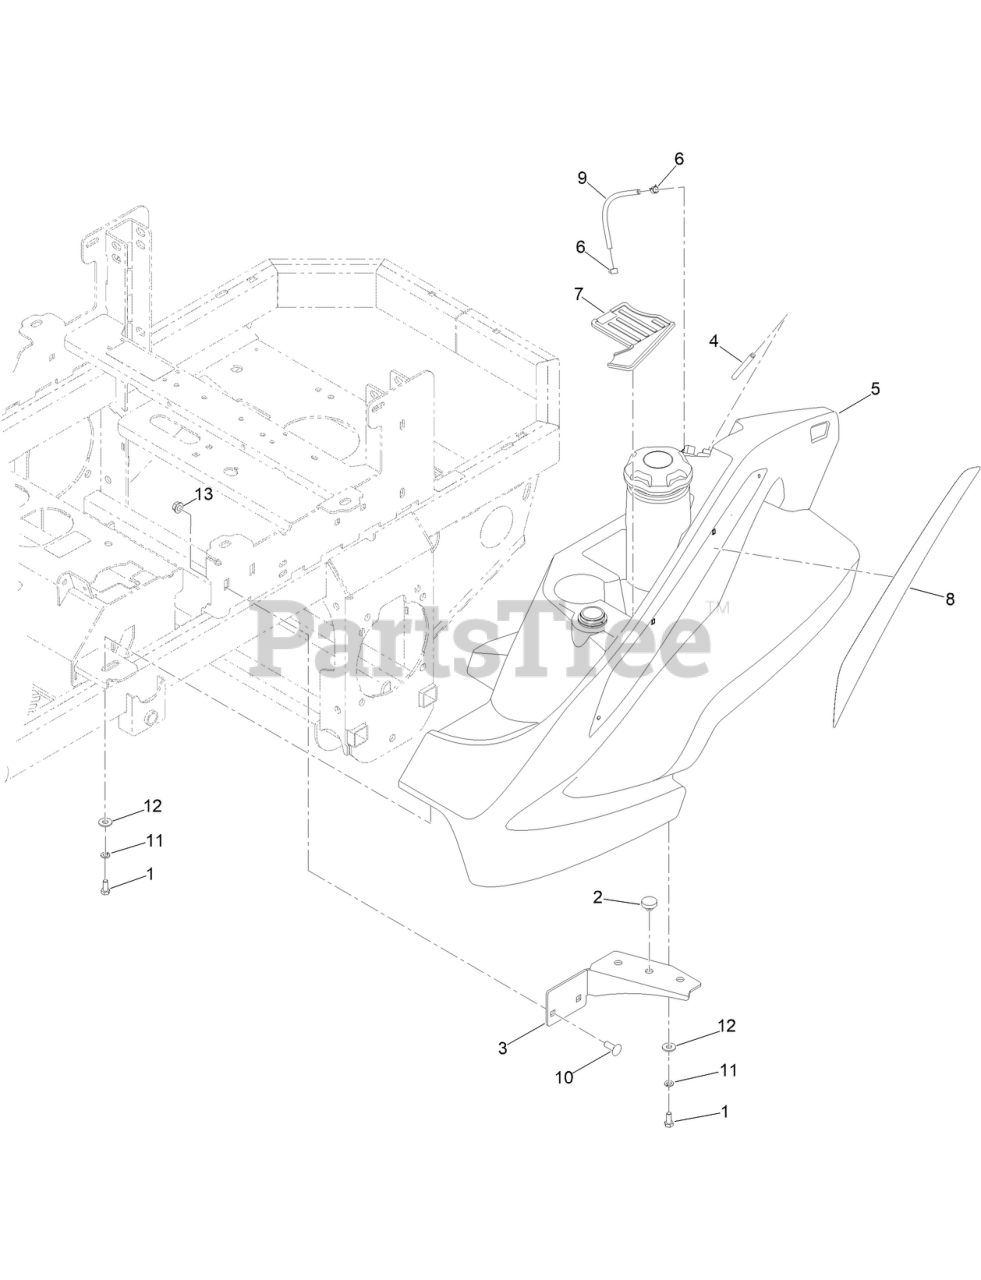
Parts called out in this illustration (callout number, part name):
1	SCREW-HH
2	PUSH-IN RUBBER BUMPER MWR FLOOR
3	RT/SRT GAS TANK SUPPORT PAINTED
4	MWR FUEL TANK BLACK 3/16IN VENT TUBE 1FT
5	MWR GASOLINE FUEL TANK ASSY
6	1/2IN (#8) HOSE CLAMP
7	RUBBER TANK STORAGE COMPARTMENT INSERT
8	MWR FUEL TANK LOGO LT SIDE
9	1/4IN SAE J30R7 BULK HOSE 1FT
10	SCREW-CARR
11	WASHER-LOCK
12	WASHER-FLAT
13	NUT-HHF, WHIZ
